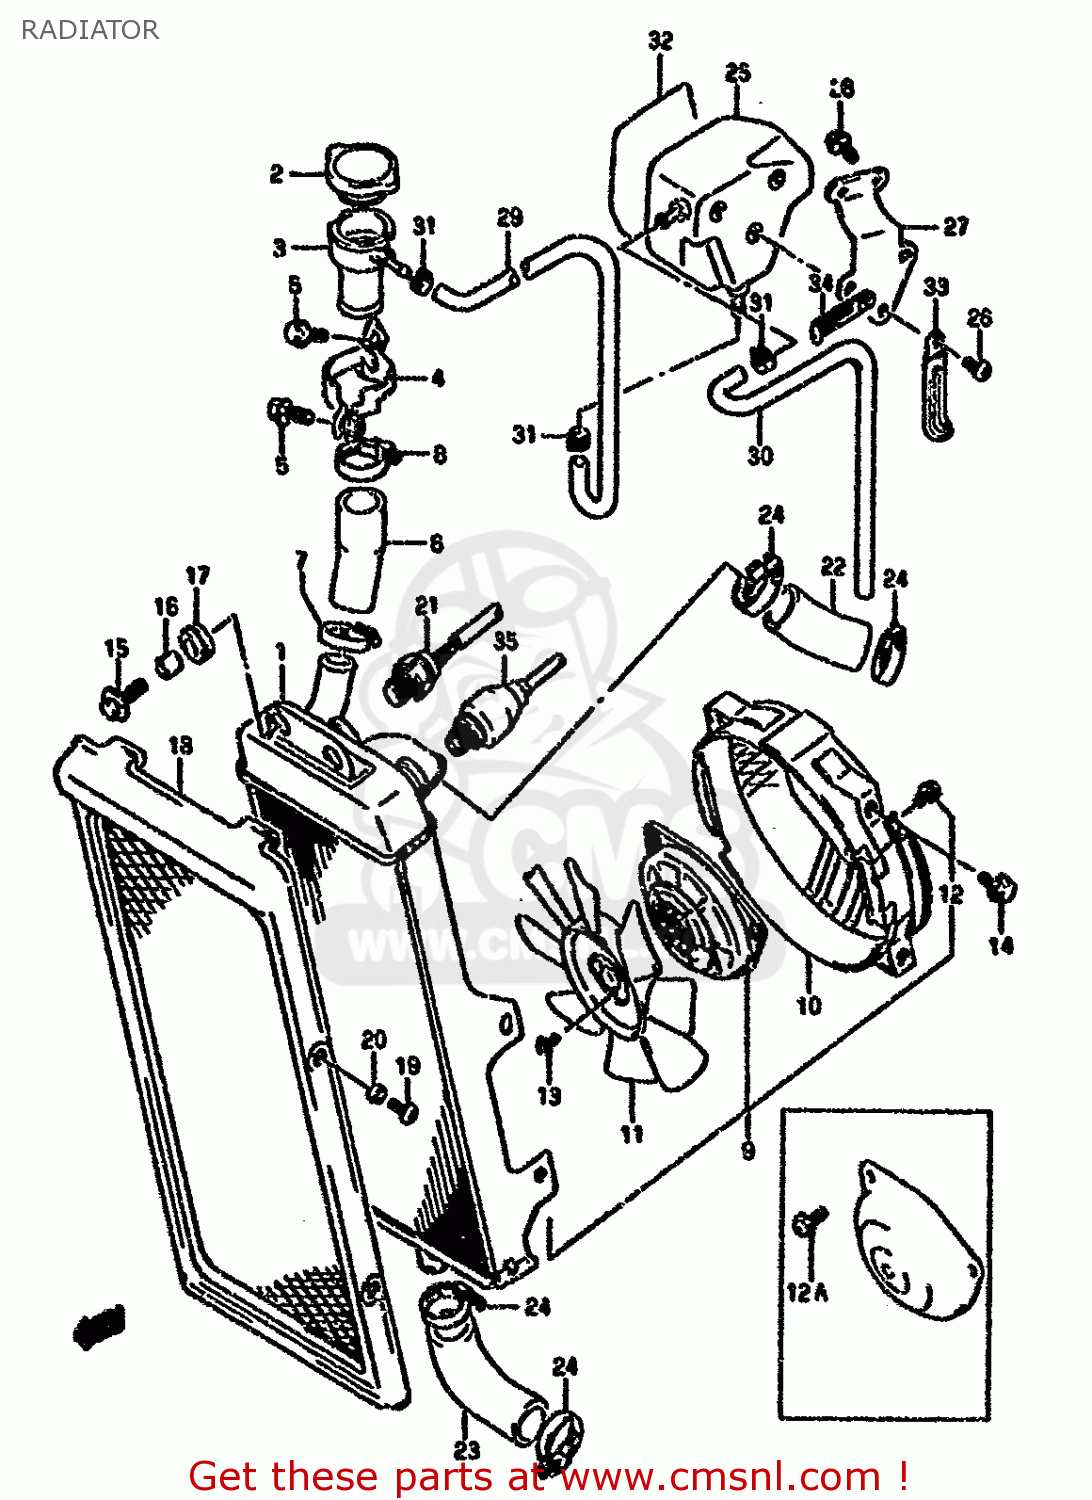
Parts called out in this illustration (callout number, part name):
1	RADIATOR ASSY,WATER
2	CAP,RADIATOR
3	CONDUCTION,RADIATOR
4	BRACKET,CONDUCTION
5	BOLT
6	HOSE,CONDUCTION
7	CLAMP
8	CLAMP
9	FAN ASSEMBLY,RADIATOR
10	SHROUD
11	FAN
12	SCREW
12A	SCREW
13	SCREW 4X6
14	BOLT
15	BOLT(6X25)
16	SPACER (6.8X10X10)
17	CUSHION
18	COVER COMP,RADIATOR
19	SCREW(6X10)
20	SPACER (6.4X9X3.5)
21	SWITCH,RADIATOR FAN
22	HOSE,RADIATOR INLET
23	HOSE,RADIATOR OUT
24	CLAMP
25	TANK,RESERVOIR
26	SCREW
27	BRACKET,RESERVOIR TANK
28	BOLT
29	HOSE,RESERVOIR TANK INLET
30	HOSE,RESERVOIR TANK INLET
31	CLIP
32	EMBLEM,RESERVOIR TANK
33	CLAMP
34	CLAMP
35	SWITCH ASSY,WATER TEMP
